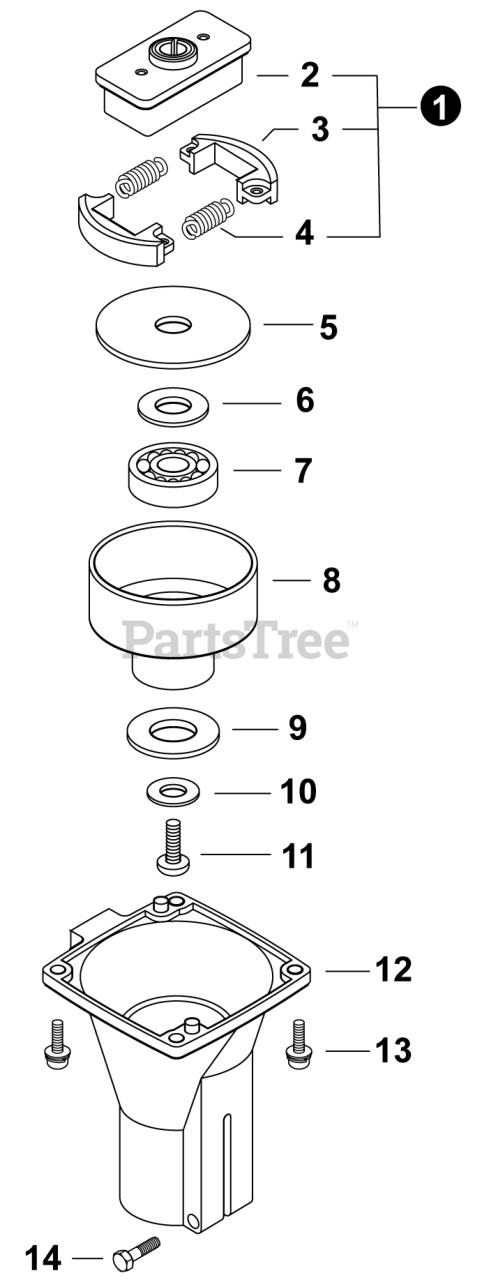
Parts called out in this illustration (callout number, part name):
1	CLUTCH ASSY
2	HUB, CLUTCH
3	SHOE, CLUTCH
4	SPRING, CLUTCH
5	PLATE, CLUTCH
6	WASHER 10.5x18x1.6
7	BEARING, BALL 6000-2RLB
8	DRUM, CLUTCH
10	WASHER, CLUTCH
11	SCREW 6x12
12	CASE, CLUTCH
13	SCREW 4x18
14	BOLT 5
